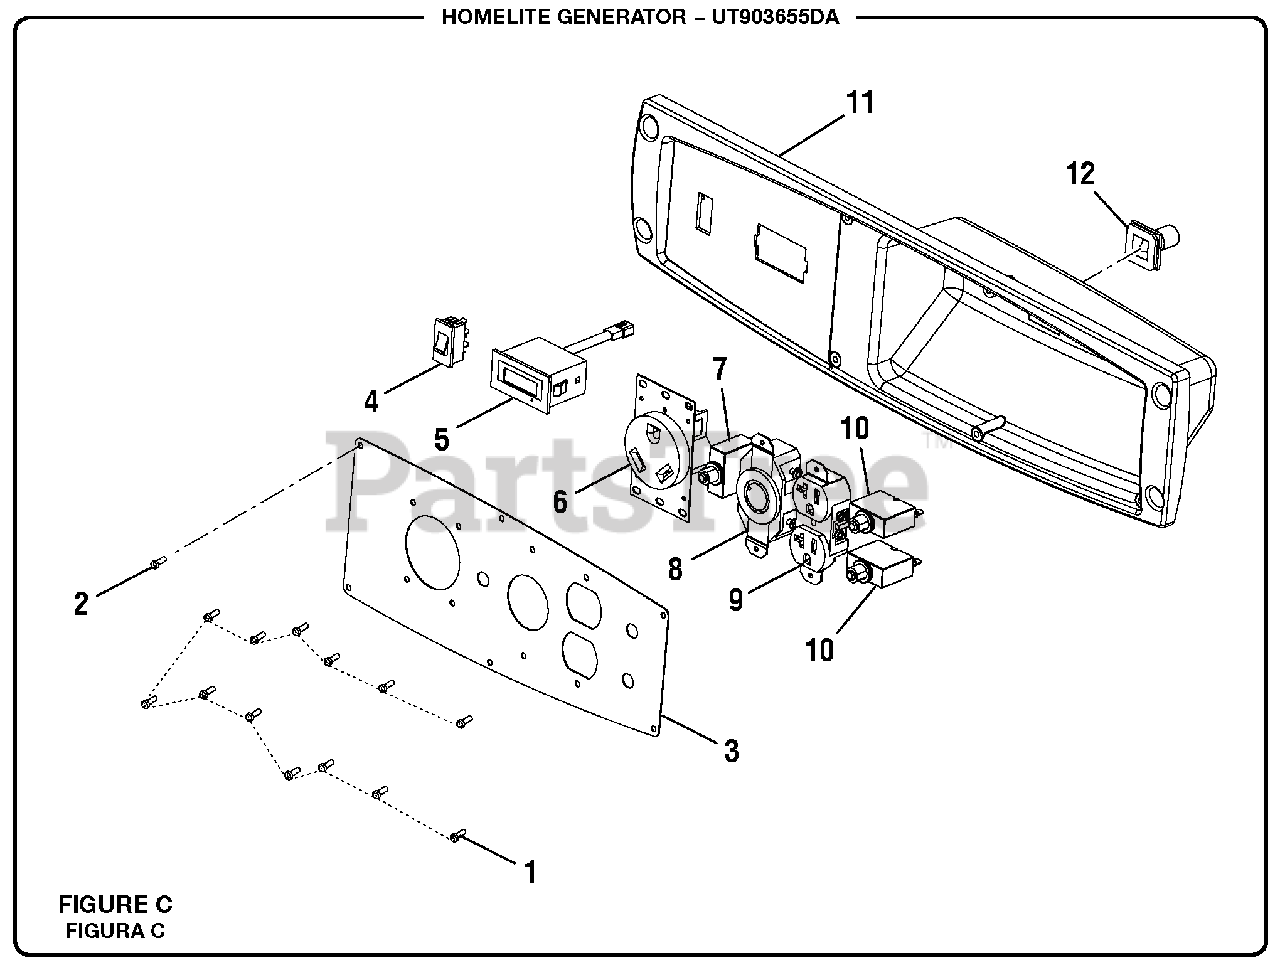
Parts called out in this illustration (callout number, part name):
1	Screw (#6-20 x 9.65 mm)
2	Screw (#6-20 x 20 mm)
3	Electrical Panel
5	Digital Display
6	120V/30A Recepticle (RV)
7	30A Circuit Breaker
8	120V/30A Recepticle (Twist Lock)
9	120V Duplex Receptacle
10	20A Circuit Breaker
11	Front Panel Assembly
12	Rubber Boot
